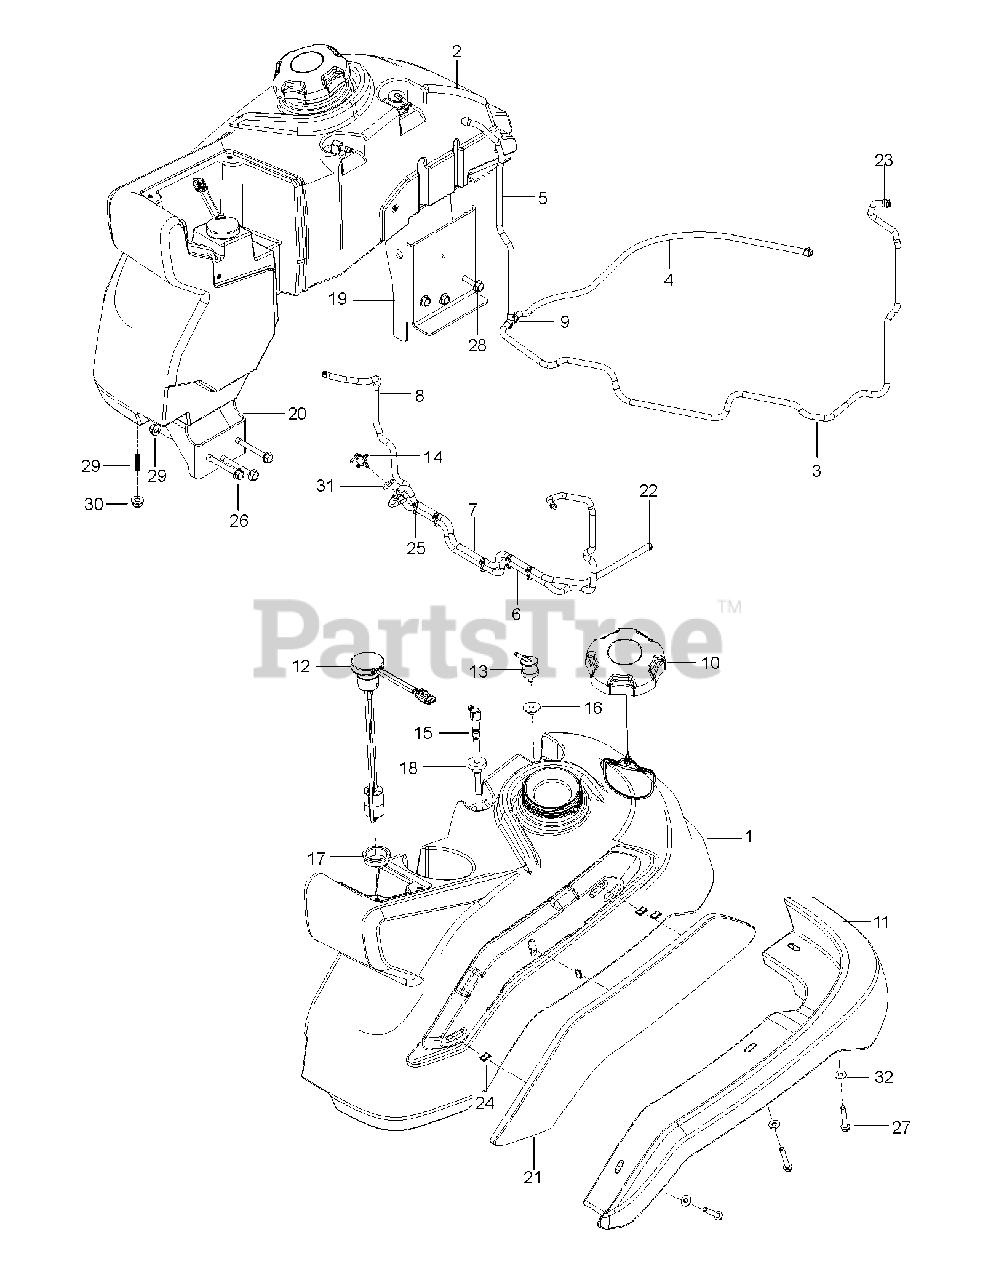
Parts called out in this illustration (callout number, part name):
1	Fuel Tank Assembly, LH
2	Fuel Tank Assembly, RH
3	HOSE.3/16".VAPOR.LINE.50"LGTH
4	HOSE.3/16".VAPOR.LINE.26"LGTH
5	HOSE.3/16".VAPOR.LINE.17"LGTH
6	HOSE.1/4".LOW.PERM.FUEL.LN.46"
7	HOSE.1/4".LOW.PERM.FUEL.LN.33"
8	HOSE.1/4".LOW.PERM.FUEL.LN.24"
9	TEE, FUEL LINE 3/16"
10	CAP, FUEL
11	GUARD.MUD.LH
12	SENSOR.FUEL.LVL.FLOAT.V500
13	VALVE.FUEL.CHECK
14	FUEL VALVE
15	TUBE.ASM.FUEL.TANK.PICK-UP.LH
16	BUSHING OUTLET T
17	GROMMET, FUEL SENSOR
18	Check Fuel Grommet
19	BRACKET.FUEL.TANK.REAR.SUP.431
20	BRACKET.FUEL.TANK.REAR.SUP.431
21	Fuel Tank Cover, LH Console App
22	HOSE CLAMP
23	CLAMP, HOSE
24	Clip, U Type
25	TIE WRAP, 8-3/8", W/CLIP
26	BOLT HEX FLGHD 5/16-18X3 GR. 5
27	SCREW.1/4-20X1.5IN.HEX.MACH
28	SCREW
29	SCREW.5/16-18X1.25"THREADED
30	5/16-18 NYLOC FLANGE NUT
31	WASHER.CLEAR.ZINC
32	WASHER
